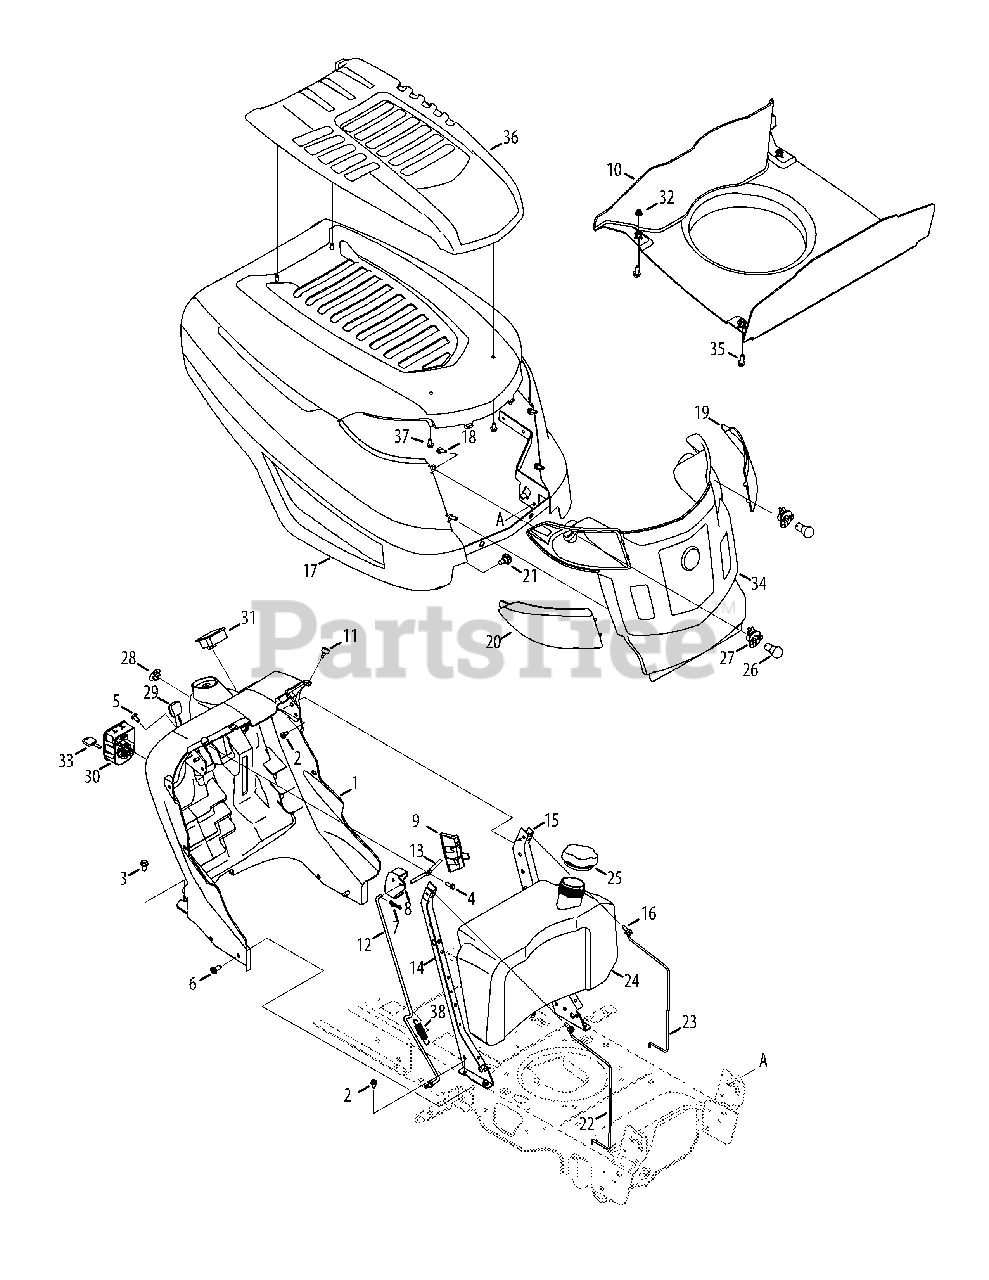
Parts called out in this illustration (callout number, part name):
1	Dash Assenbly
2	Taptite Screw ,1/4-20 x 0.500
3	Taptite Screw ,5/16-18 x .750
4	Hi-Lo Screw, 1/4-15 x 0.750
5	Screw, 1/4-14 x 0.625
6	Taptite Screw ,5/16-18 x 0.750
7	Bow Tie Cotter Pin
8	Dash Lever
9	Cruise Cover
12	Control Rod
14	RH Support Plate
15	LH Support Plate
16	Tap Screw, 1/4-20, 0.625
17	Hood Assembly
18	Screw, 1/4 DIA x .750
21	Shoulder Screw, .43 x .29
22	LH Tank Support Rod
23	RH Tank Support Rod
27	Lamp Socket
28	Choke Plug
29	Throttle/Choke Cable, 46.5"
30	Module Switch, Ignition
31	Hour Meter
32	Flangelock Nut, 1/4-20
33	Key, Assembly
35	Hex Screw, 1/4-20 x .620
37	Hex Washer Screw, 1/4-15 x .50
38	Spring, .500 Dia. x 2.733
